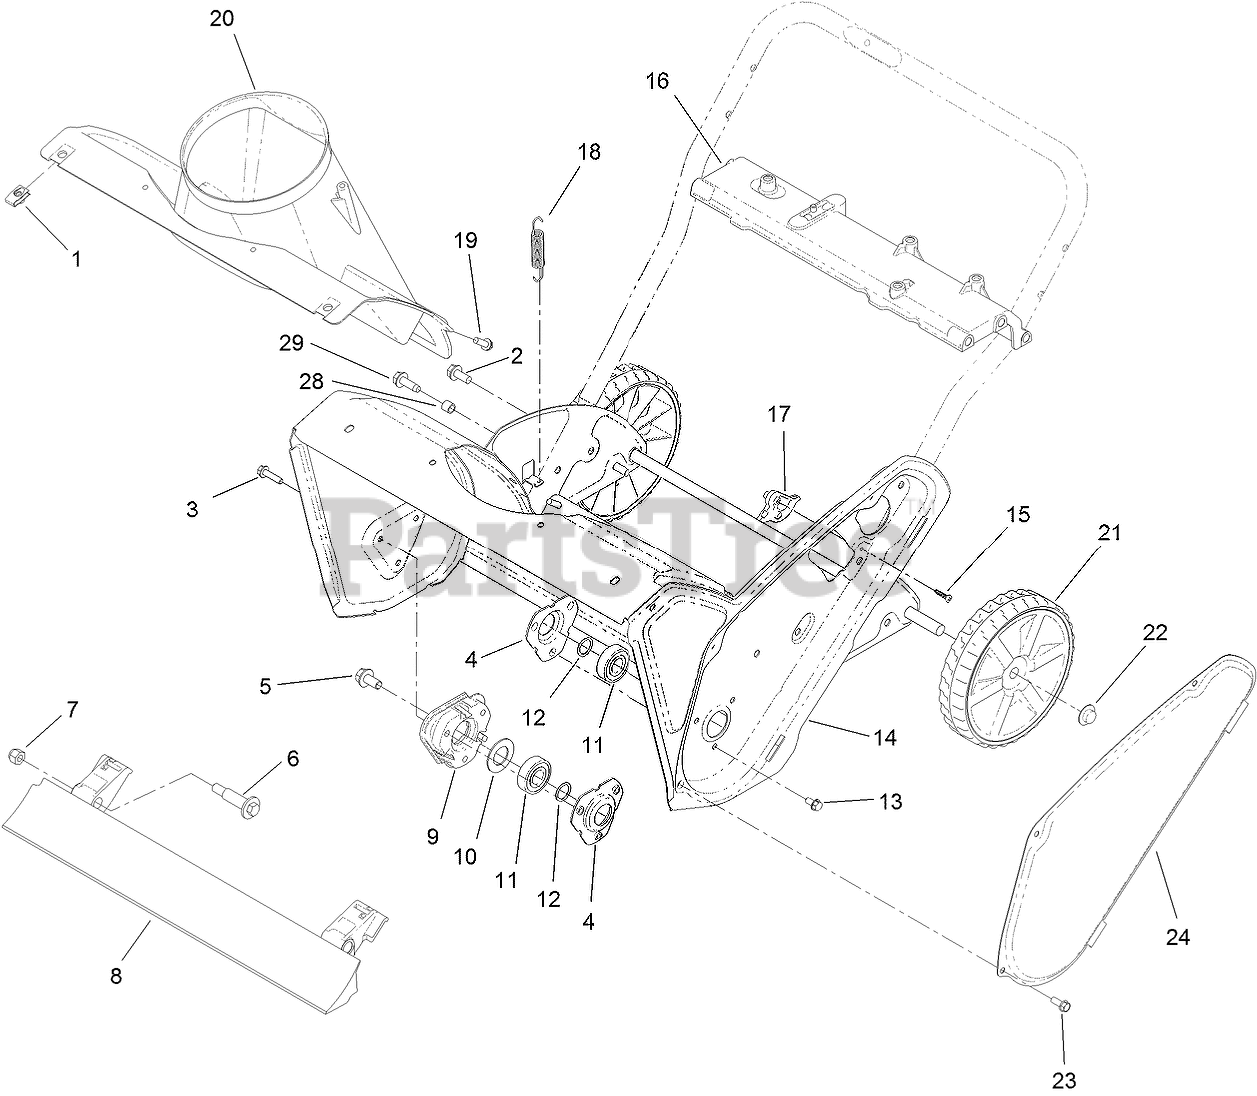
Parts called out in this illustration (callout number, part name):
2	SCREW-HWHTF
3	SCREW-HWHTF
4	FLANGE-BEARING
5	SCREW-HWH
6	BOLT-WHEEL
7	NUT-LOCK, NI
8	BLADE-SCRAPER
9	SPACER-BEARING, RH
10	WASHER-RUBBER
11	BEARING-BALL
12	WASHER-THRUST
13	SCREW-HWH
14	HOUSING-AUGER
15	SCREW-PPH
16	BRACE-FRAME
17	GUIDE-CABLE, CLUTCH
18	SPRING-EXTENSION
19	SCREW-HWH
20	CHUTE-LOWER
21	WHEEL ASM
22	NUT-PUSH
23	SCREW-HWH
24	COVER-BELT
28	SPACER
29	SCREW-HWHTF
